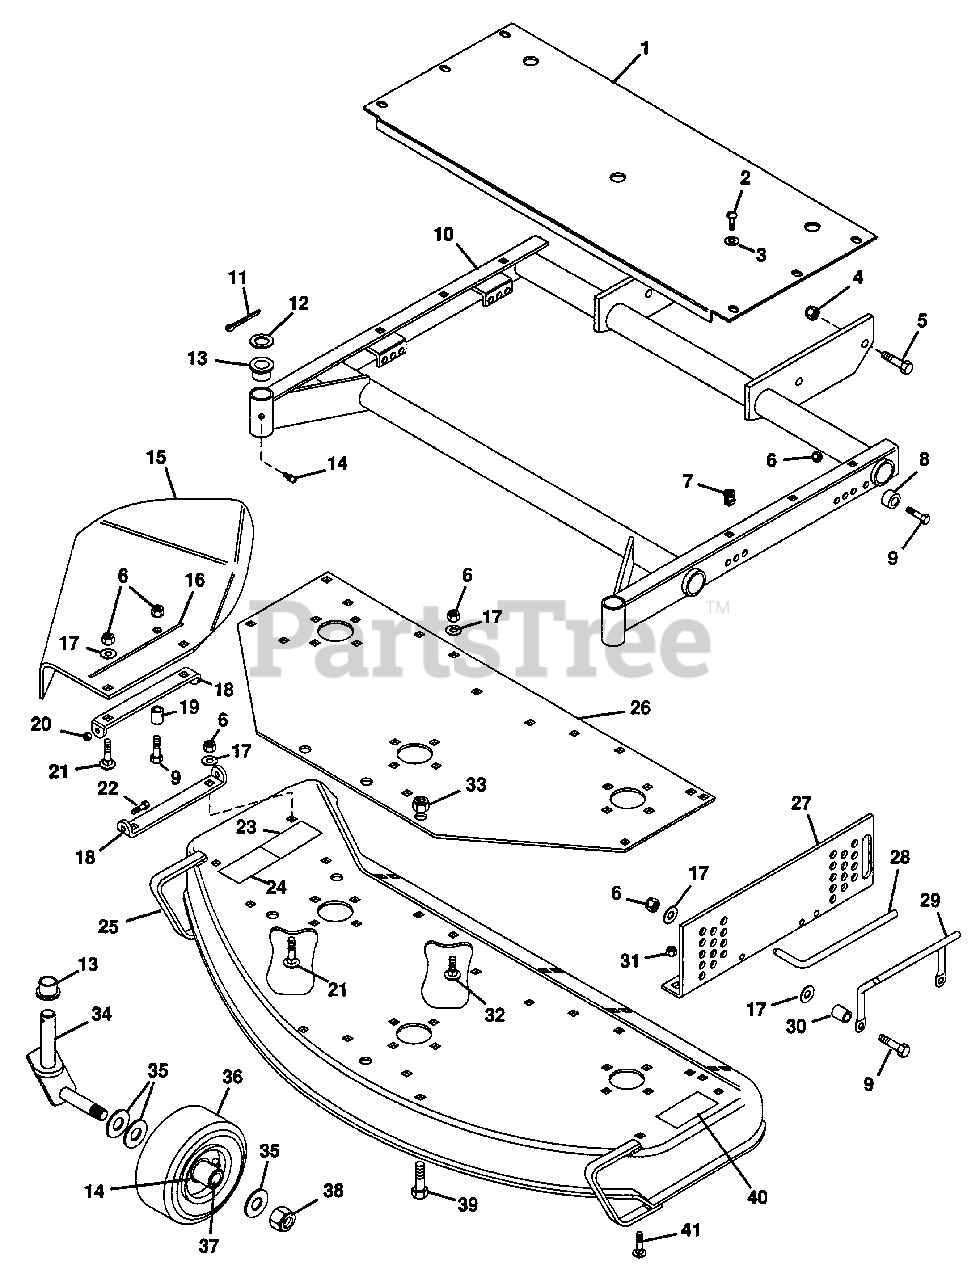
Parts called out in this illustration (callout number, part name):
1	Guard, 50" Mower Belt
2	Screw, 1/4-20x.50 Self Tapping
3	Washer, Flat .281x.625x.065
4	Nut, Lock 5/8-11
5	Bolt, Hex 5/8-11x1.50
6	Nut, Lock 3/8-16
7	Grommet, Plastic
8	Bushing, St. .391x.621x.676 Stl.
9	Bolt, Hex 3/8-16x1.50
10	Weldment, Mower Frame
11	Pin, Cotter .187x1.50
12	Race, Bearing Thrust
13	Bushing, Flange Nylon
14	Fitting, Lube 1/4-28
15	Shield, Safety Ext. 50" Mower
16	Decal, Width of Cut
17	Washer, Flat .406x.812x.065
18	Bracket, Chute
19	Stop, Chute
20	Nut, Lock 1/4-20
21	Bolt, 3/8-16x1.00 Rd Hd Sq Nk
22	Bolt, Hex 1/4-20x.875
23	Decal, Danger Hand
24	Decal, Warning Eye
25	Weldment, 50" Mower Deck
26	Plate, Support
27	Bracket, Mower Side Support L.H.
28	Pin, Mower Locking
29	Handle
30	Bracket, Mower Side Support R.H.
30	Bushing
31	Nut, Lock 5/16-18
32	Bolt, Carriage 3/8-16x.75
33	Nut, Lock 1/2-13
34	Weldment, Caster Fork
35	Washer, Flat .812x1.496x.134
36	Wheel, Gauge
37	Bearing, Gauge Wheel
38	Nut, Lock 3/4-10
39	Bolt, Hex 1/2-13x1.25
40	Decal, Danger Foot
41	Bolt, Carriage 5/16-18x1.00
